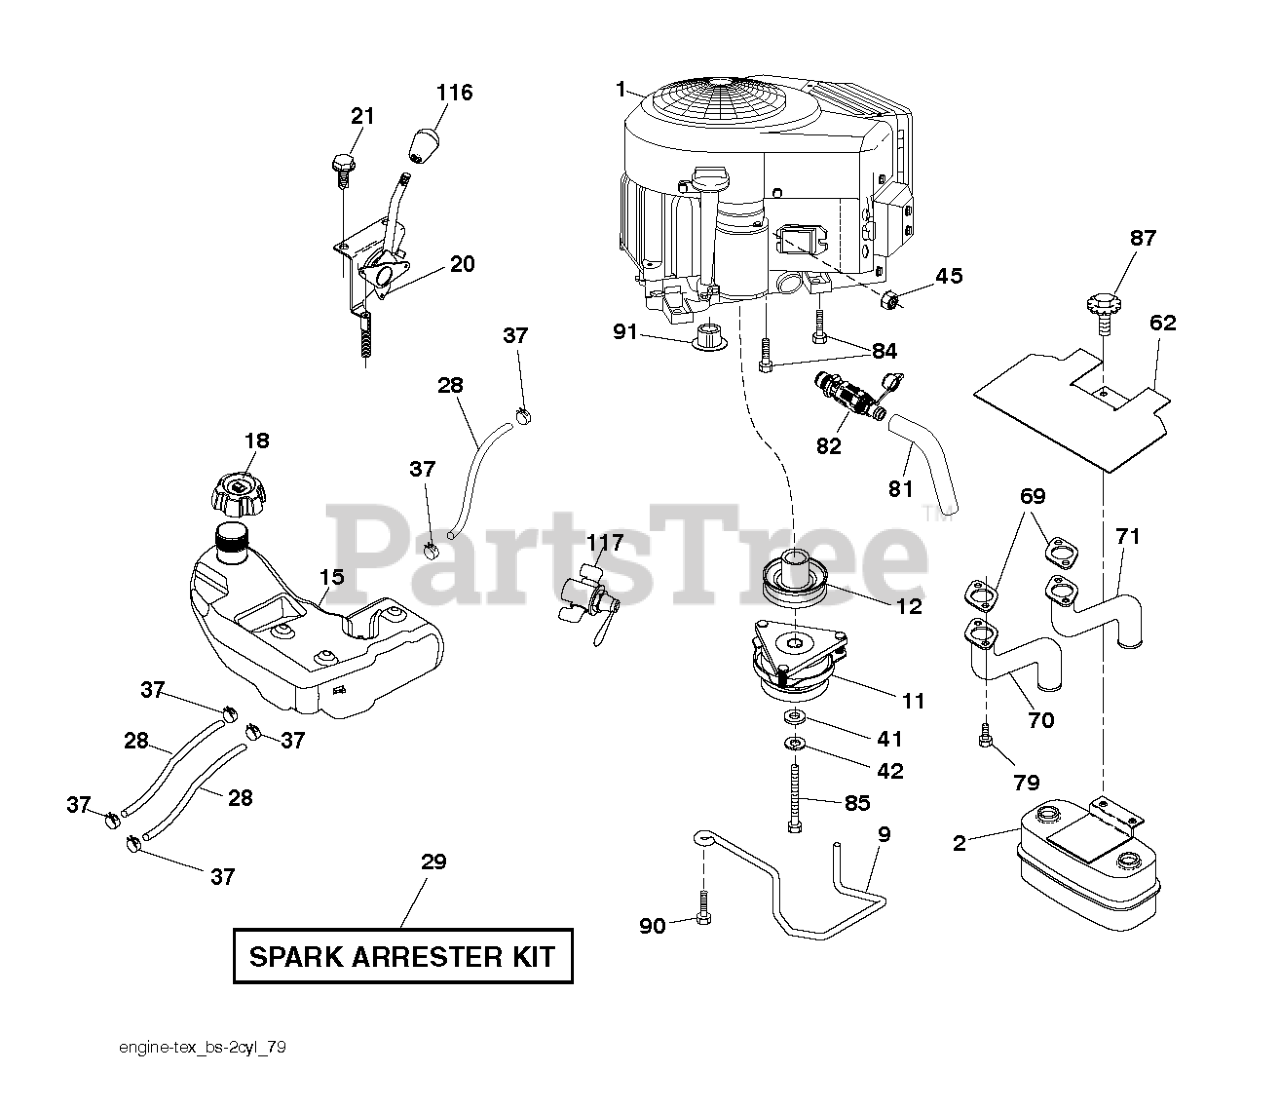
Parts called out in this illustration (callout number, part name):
2	MUFFLER.TWIN.CYL.LOW.TONE
9	KEEPER BELT ENGINE
11	CLUTCH MZ ZTR GT.48/54"1.125"
12	PULLEY ENGINE
18	CAP.ASSY.FUEL.3".N-EPA.GRY.498
20	CONTROL.THROTTLE/CHOKE.PRO.45
21	SCREW.#10 X 0.750.BOS
28	REPL BY 532 00 85-43
29	KIT.SPARK ARRESTOR 794945 B&S
37	HOSE CLAMP
42	LOCKWASHER
45	NUT
62	SHIELD.HEAT.MUFFLER
69	GASKET.MUFFLER
70	EXHAUST.TUBE.LH.BS/TWIN
71	EXHAUST.TUBE.RH.B&S.TWIN.INTEK
79	SCREW.SOCKET.HEAD.5/16-18
81	TUBE, DRAIN OIL ASM.
82	VALUE.OIL.DRAIN
84	SCREW.3/8-16
85	BOLT HEX 7/16-20 X 3.75 GR. 5
87	BOLT.5/16-18UNCX1.W/SEMS.BLK
90	SCREW 3/8-16X1
91	BUSHING.1.375OD
116	KNOB - SHIFT
117	VALVE FUEL RESERVE
